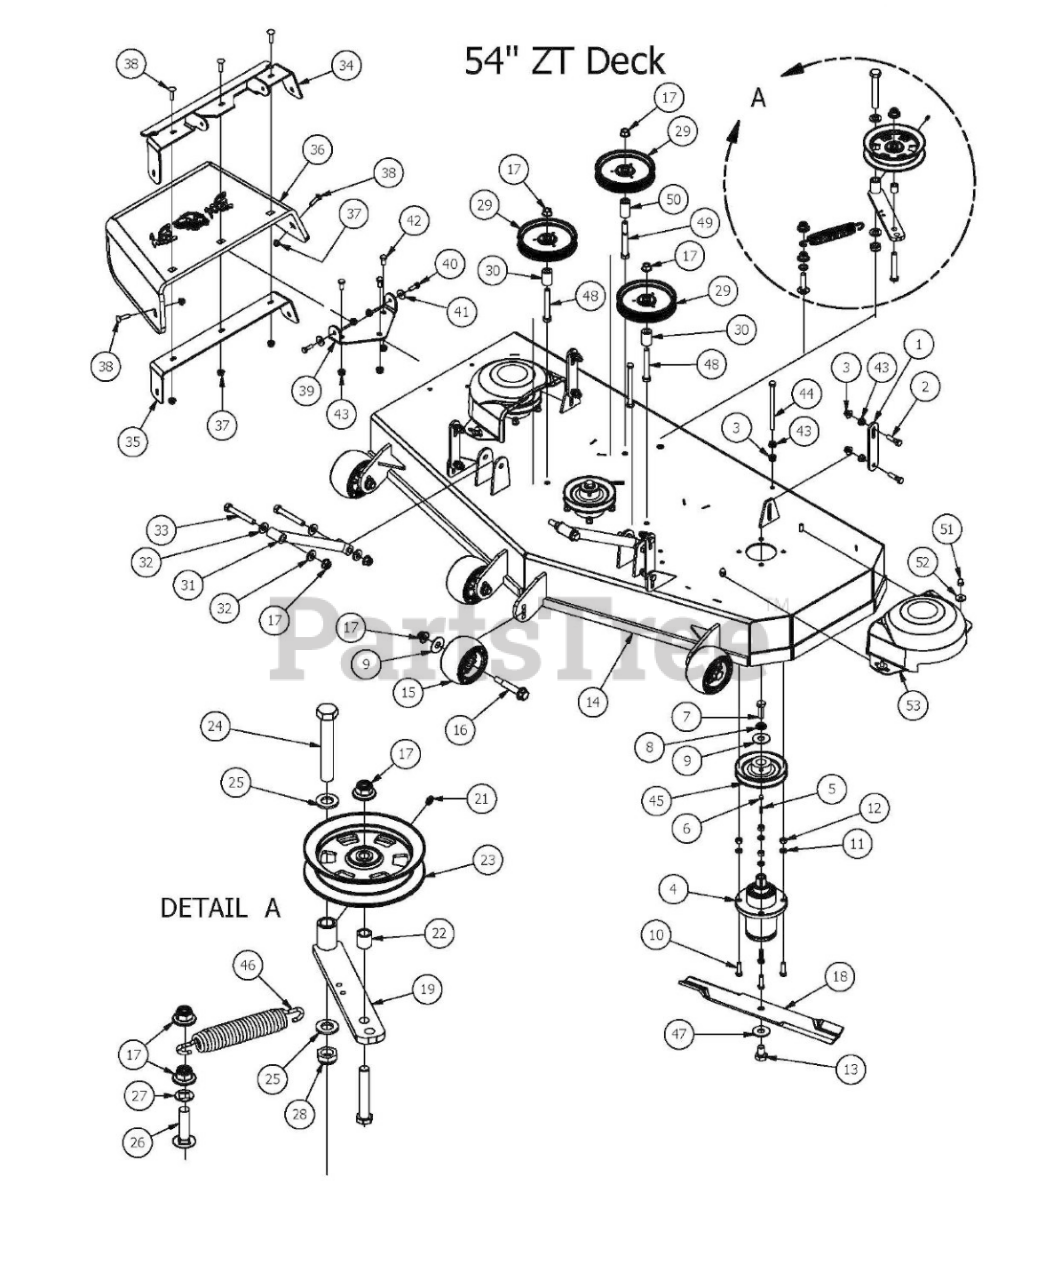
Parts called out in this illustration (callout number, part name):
1	2017 MZ/ZT Deck Hanger
2	3/8" x 1 1/2" Hex Bolt
3	3/8" Nylock Flange Nut
4	Spindle Assembly
5	1/4" x 1" Key
6	5/16 Set Screw
7	1/2"-20 x 1 1/2 - Grade 5 Fine Thread Bolt
8	1/2" Lock Washer Zinc
9	1/2" Belleville Washer
10	3/8" x 1 1/4" Hex Bolt
11	3/8" Lock Washer
12	3/8" Hex Nut
13	5/8" x 1 1/2" Grade 8 Hex Bolt (Fine)
14	54 ZT Welded Deck Shell
15	Deck Wheel
16	Deck Wheel Bolt
17	1/2-13 Nylon Flange Nut
18	54" Deck Fusion Blade For Outlaw
19	Deck Idler
20	1/2-13 x GR 5 Hex Bolt Zinc
21	1/4" Press in Grease Fitting
22	Spacer 3/4 OD x 1/2 ID x 3\4 Length
23	5" Idler Pully
24	5/8" x 4" Hex Bolt
25	.630 ID Plastic Washer
26	1/2 x 2" Carriage Bolt
27	.517 Square Hole Round Washer
28	5/8-11 Nylon Insert Jam Half Nut
29	5-3/4 Idler Pulley-Capitol Stampings
30	Idler Pulley Standoff
31	Deck Locator
32	.505 Nylon Spacer
33	1/2-13 x 3 1/2 GR 5 Hex Bolt
34	Discharge Upper Chute Bracket
35	Discharge Lower Chute Bracket
36	Rubber Discharge Chute
37	5/16" Nylon Flange Nut
38	5/16" x 1 1/4" Carriage Bolt
39	Discharge Chute Hanger (Deck Mounted)
40	5/16" x 1" Bolt
41	.360 ID Plastic Washer
42	3/8" x 3/4" Hex Bolt
43	3/8" Flange Nut
44	3/8-16 x 5 1/2 Hex Bolt
45	5.25" Deck Spindle Pulley
46	2015 Deck Idler Spring
47	5/8" Flat Washer
48	1/2 x 3 1/2 Flange Bolt Grade 8
49	1/2" x 4" Bolt (Grade 8)
50	1 3/4" Pulley Spacer
51	Acorn nut-pulley Cover
52	.360 ID Plastic Washer-Black
53	Pulley Cover
